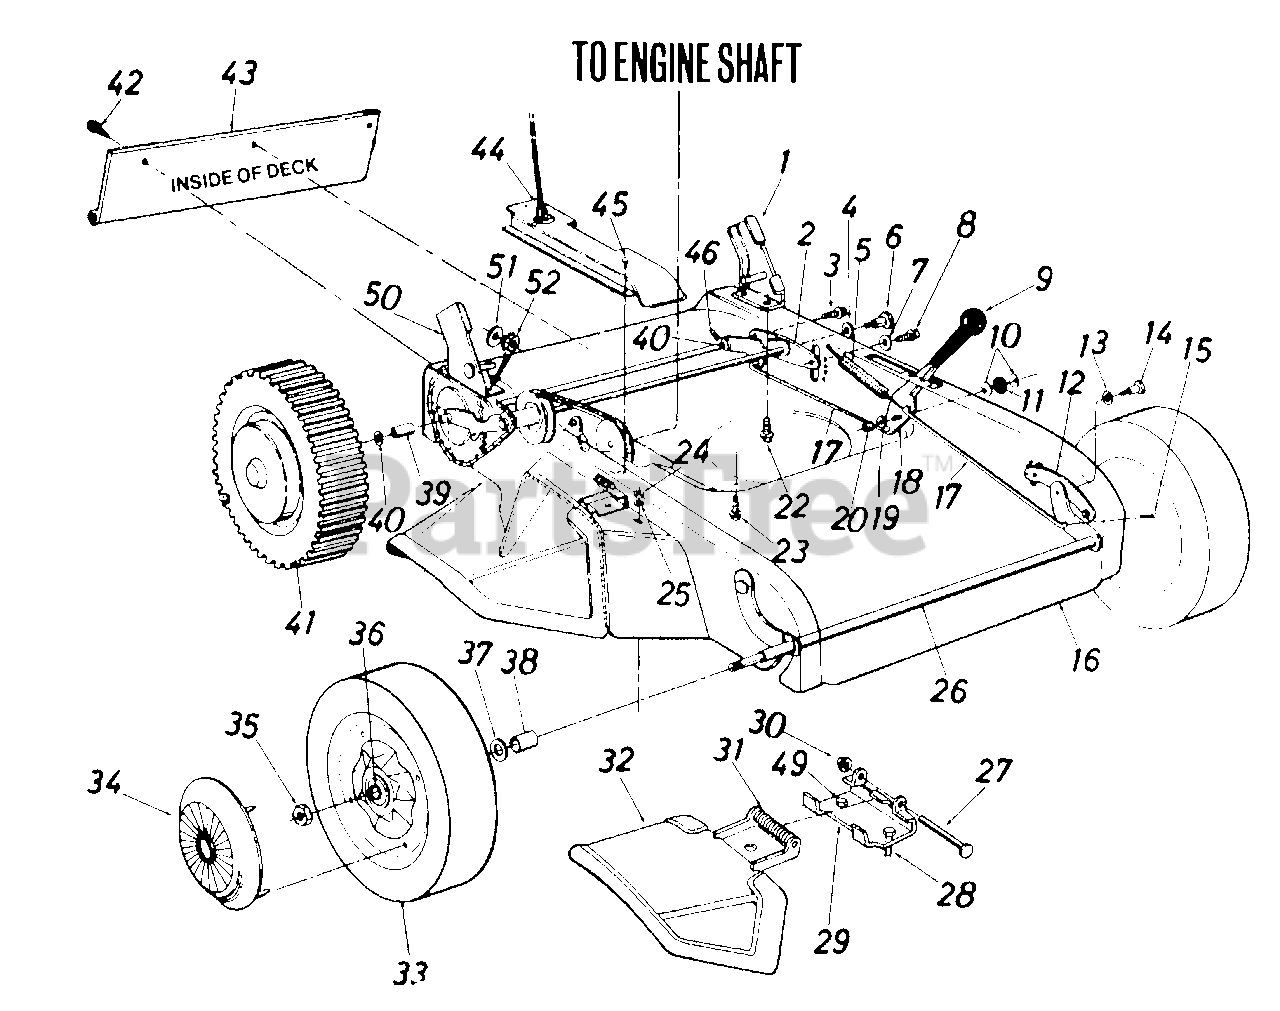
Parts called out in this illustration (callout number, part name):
1	Handle Mount Brkt. Ass'y - L.H.
2	Rear Pivot Brkt.
3	Hex Wash. Hd. TT-Tap Scr. 3/8-16 x 1" Lg.
4	Int. L-Wash. 3/8 I.D.
5	Extension Spring
6	Shld. Bolt .625 Dia. x .425
7	Belleville Washer
8	Hex Wash. Hd. TT-Tap Scr. 3/8-16 x 1" Lg.
9	Grip - Black
10	Belleville Washer
11	Rubber Washer
12	Front Pivot Brkt.
13	Int. L-Washer 3/8 I.D.
14	Shld. Bolt .625 Dia. x .425
15	Cotter Pin 3/32 x 3/4 Lg.
16	Upper Deck Ass'y.
17	Height Adj. Rod
18	Height Adj. Lever
19	Fl-Wash. .531 I.D. x .93 O.D.
20	Hex Jam Nut 3/8-24 Thd.
22	Hex Wash. Hd. B-Tap Scr. 5/16-18 x .5" Lg.
23	Hex Wash. Hd. TT-Tap Scr. 3/8-16 x 1" Lg.
24	Hex Nut 5/16-18 Thd.
25	L-Wash. 5/16" I.D.
26	Front Axle Ass'y.
27	Pivot Pin
28	Hex B-Tap Scr. 1/4 x .38 Lg.
29	Adapter Plate
30	Cap Speed Nut 1/4" Rod
31	Torsion Spring
32	Chute Deflector Ass'y. - Comp.
33	Wheel Ass'y. Comp. 8 x 1.75
34	Hub Cap - Front
35	Hex Ins. L-Nut 1/4-20 Thd.
36	Flanged Ball Brg. .500" I.D.
37	Fl-Wash. .531 I.D. x .93 O.D.
40	Fl-Wash. .531 I.D. x .93 O.D.
41	Wheel Ass'y. Comp. 8 x 1.75
42	Hex Bolt, 1/4-20 x .75" Lg.
43	Rear Flap Ass'y.
44	Belt Guard
45	Hex Self-Tap Scr. #10 x .50" Lg.
46	Cotter Pin 1/8" Dia. x 1.0" Lg.
49	Hex Wash. Hd. AB-Tap Scr. 1/4 x .62" Lg.
50	Handle Mount Brkt. Ass'y. - R.H.
51	Fl-Wash. .281 I.D. x .73 O.D.
52	Sems Nut 1/4-20 Thd.
